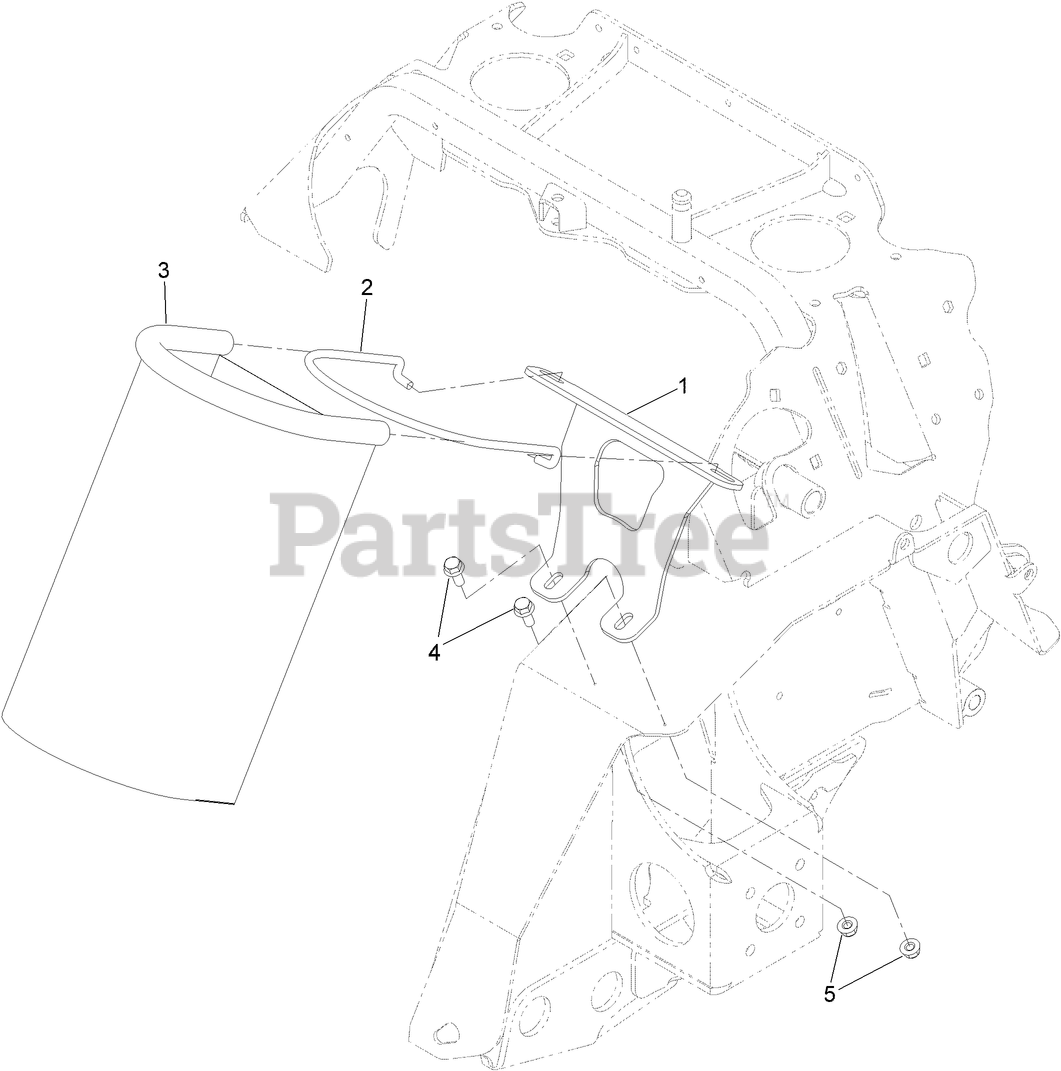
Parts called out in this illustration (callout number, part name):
1	MOUNT, TRASH CAN
2	ROD-BAG, TRASH
3	BAG-STORAGE
4	SCREW-HHF
5	NUT-HF, NI
